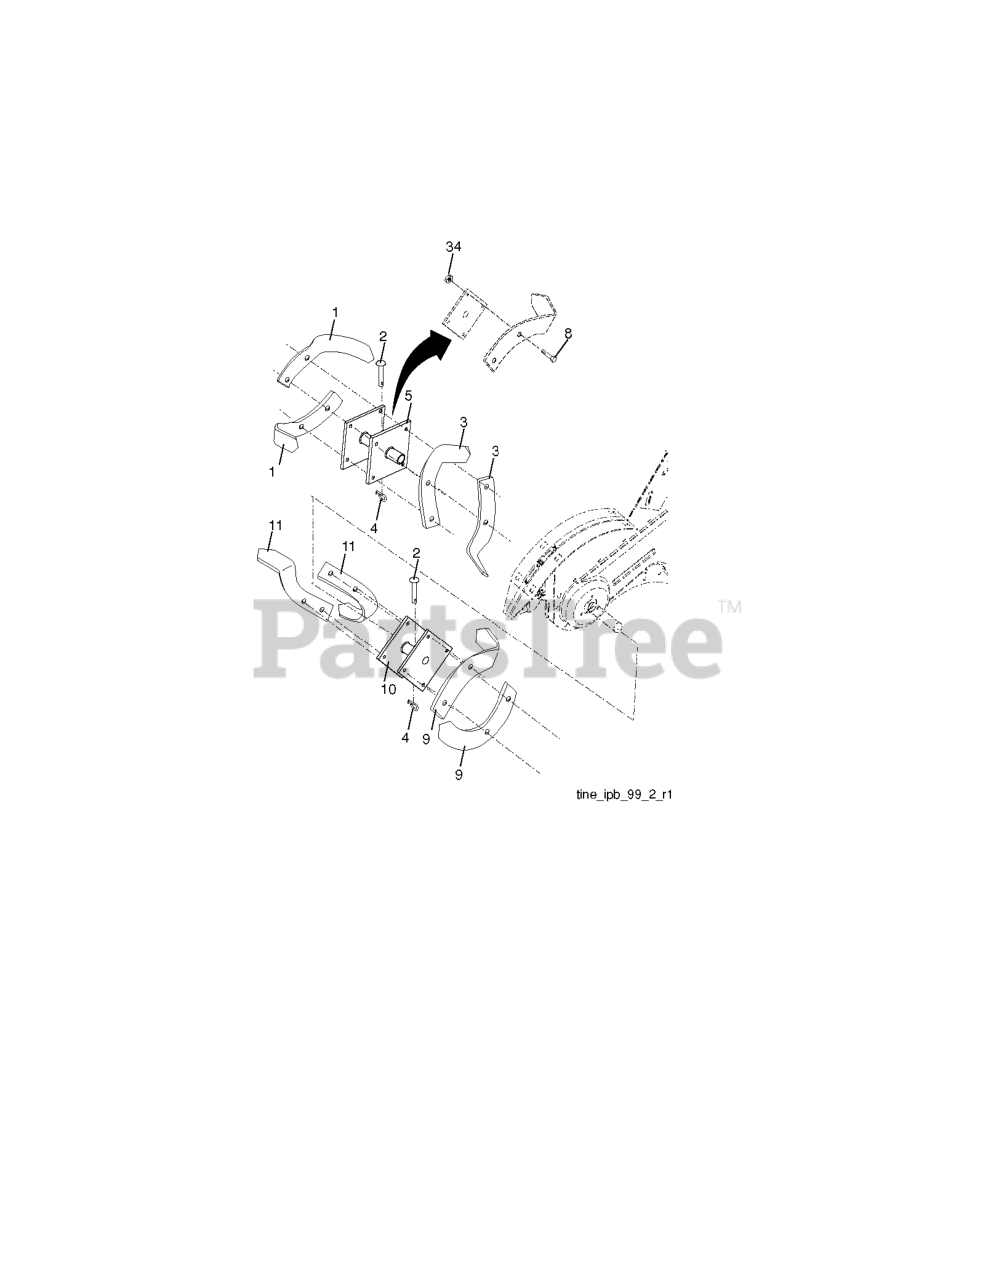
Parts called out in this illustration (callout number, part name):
1	TINE TI
2	PIN RETAINING SCREW
3	TINE.LH.12"(72L)
4	SPRING RETAINER
5	HUB.&.PLATE.LH.TILLER.BLACK
8	BOLT.HEX.001X20.37-24X1.ZINC
9	TINE TI
10	HUB.ASM.RH.14".BLACK.TILLER
11	TINE.RH.12"(72R)
34	NUT CROWNLOCK 3/8-24
